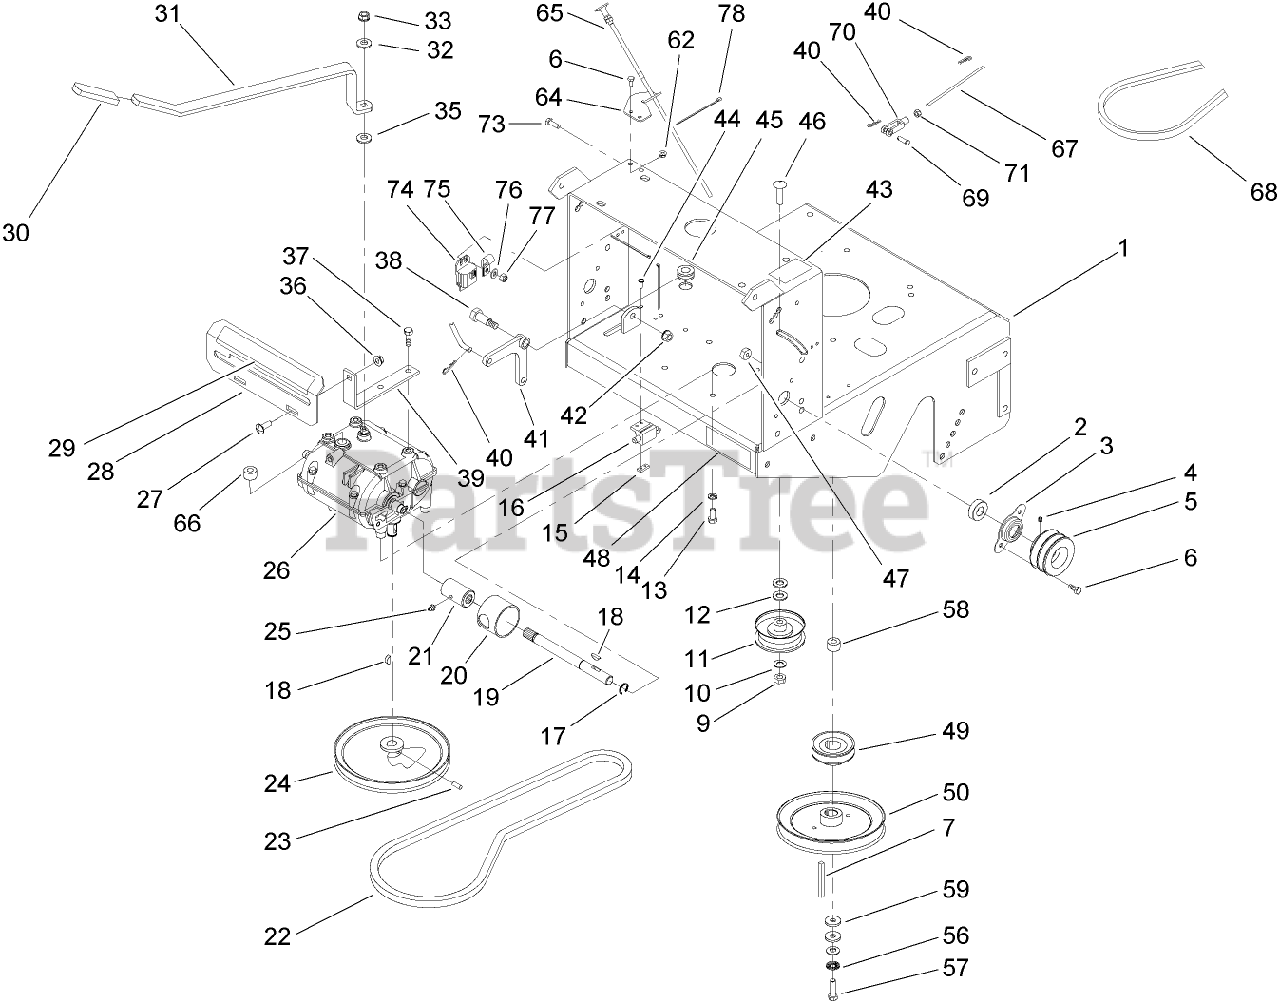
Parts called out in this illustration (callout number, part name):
1	DECK-ENGINE
2	BEARING-SHAFT
3	FLANGE-OUTPUT
4	SCREW-SET
5	SHEAVE-TRANSMISSION
6	SCREW-HH
9	NUT-LOCK, NI
10	WASHER-FLAT
11	PULLEY-IDLER, FLAT
12	WASHER-FLAT
13	SCREW-HH
14	WASHER-LOCK
15	PLATE-TAPPED
16	SWITCH-OPEN, NORMALLY
17	RING-RETAINING
18	KEY-WOODRUFF
19	SHAFT-TRANSMISSION
20	GUARD-COUPLER
21	COUPLER
22	V-BELT
23	SCREW-HSH
24	SHEAVE-TRANSMISSION
25	FITTING-GREASE
26	TRANSMISSION
27	BOLT-CARR
28	PLATE-SHIFT
29	DECAL-SPEED, GROUND
30	GRIP-LEVER
31	LEVER-SHIFT
32	WASHER-BELLEVILLE
33	NUT-LOCK
35	WASHER
36	NUT-HF
37	SCREW-HWH, THREAD CUT
38	BOLT-SHOULDER
39	BRACKET-PLATE, SHIFT
40	PIN-COTTER
41	BELLCRANK
42	NUT-HF
43	DECAL-SHUT OFF, FUEL
44	SCREW-PPH
45	GROMMET
46	SCREW-CARR
47	NUT-LOCK, NI
48	DECAL-CAUTION
49	Sheave-Transmission
50	Sheave
56	WASHER-SPRING
57	SCREW-HH
58	SPACER-CLUTCH
59	WASHER
62	NUT-HF
64	Bracket-Cable, Choke
65	Cable-Choke
66	Switch-Start, Neutral
67	ARM-ASSIST, LINKAGE
68	BELT-V
69	PIN-CLEVIS
70	YOKE-ADJUSTABLE
71	NUT-HEX
73	SCREW-HH
74	MODULE-INTERLOCK
75	CLIP-LOOM
76	WASHER-FLAT
77	NUT-LOCK, NI
78	TIE-PLASTIC
